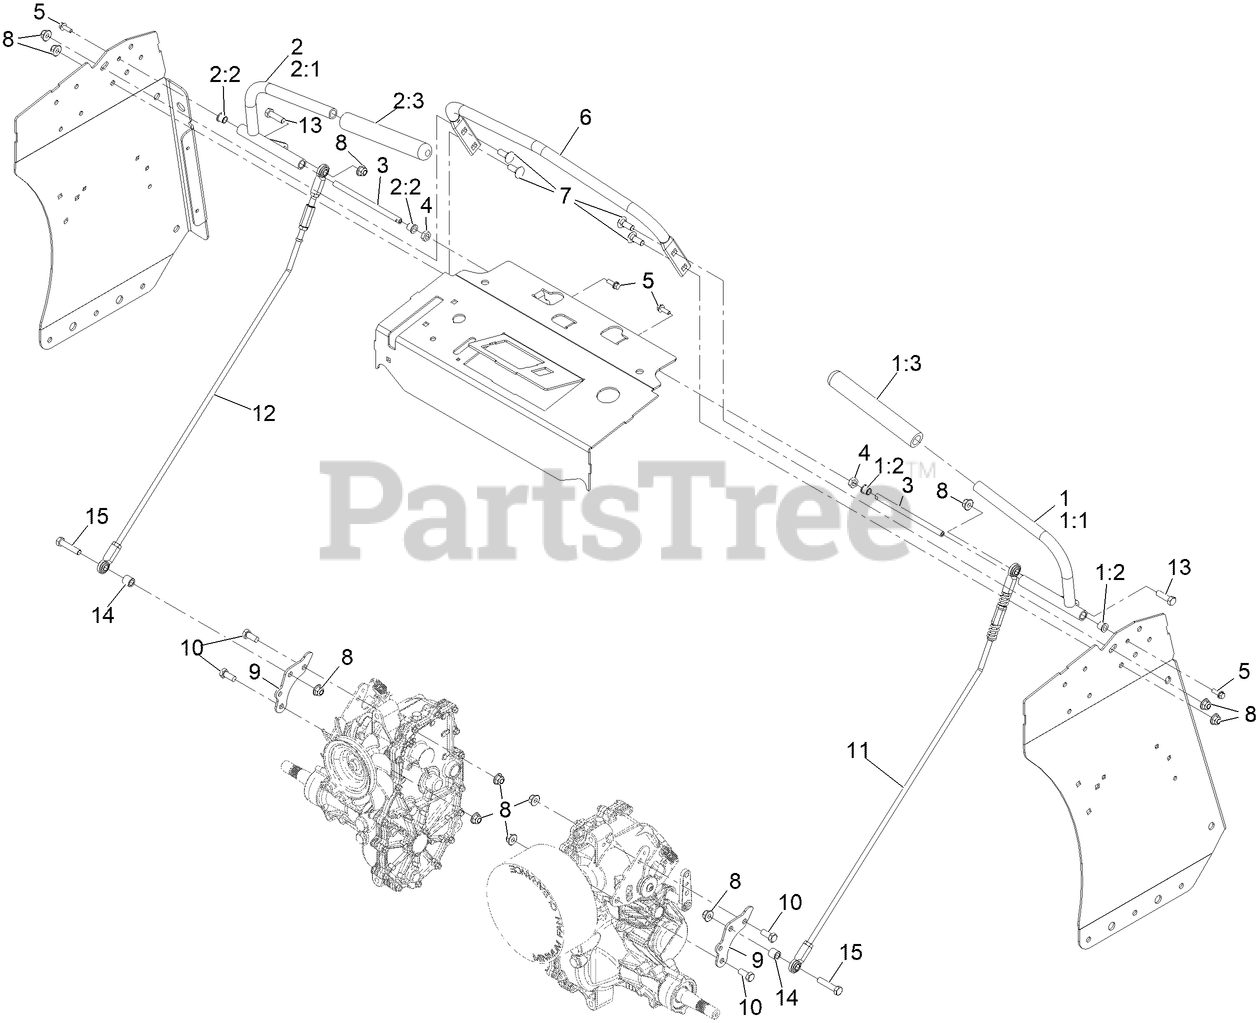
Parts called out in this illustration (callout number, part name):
1	LH MOTION HANDLE ASM
1:1	HANDLE-CONTROL, LH
1:2	BEARING
1:3	GRIP-LEVER, CONTROL
2	RH MOTION HANDLE ASM
2:1	HANDLE-CONTROL, RH
2:2	BEARING
2:3	GRIP-LEVER, CONTROL
3	SHAFT-PIVOT, MOTION CONTROL
4	SPACER-SHAFT, DRIVE LEVER
5	SCREW-HHF
6	BAR-REFERENCE
7	BOLT-CARR
8	NUT-HF, NI
9	ARM-MOTION
10	SCREW-HH
11	LH MOTION LINKAGE ASM
12	RH MOTION LINKAGE ASM
13	SCREW-HH
14	SPACER
15	SCREW-HH
